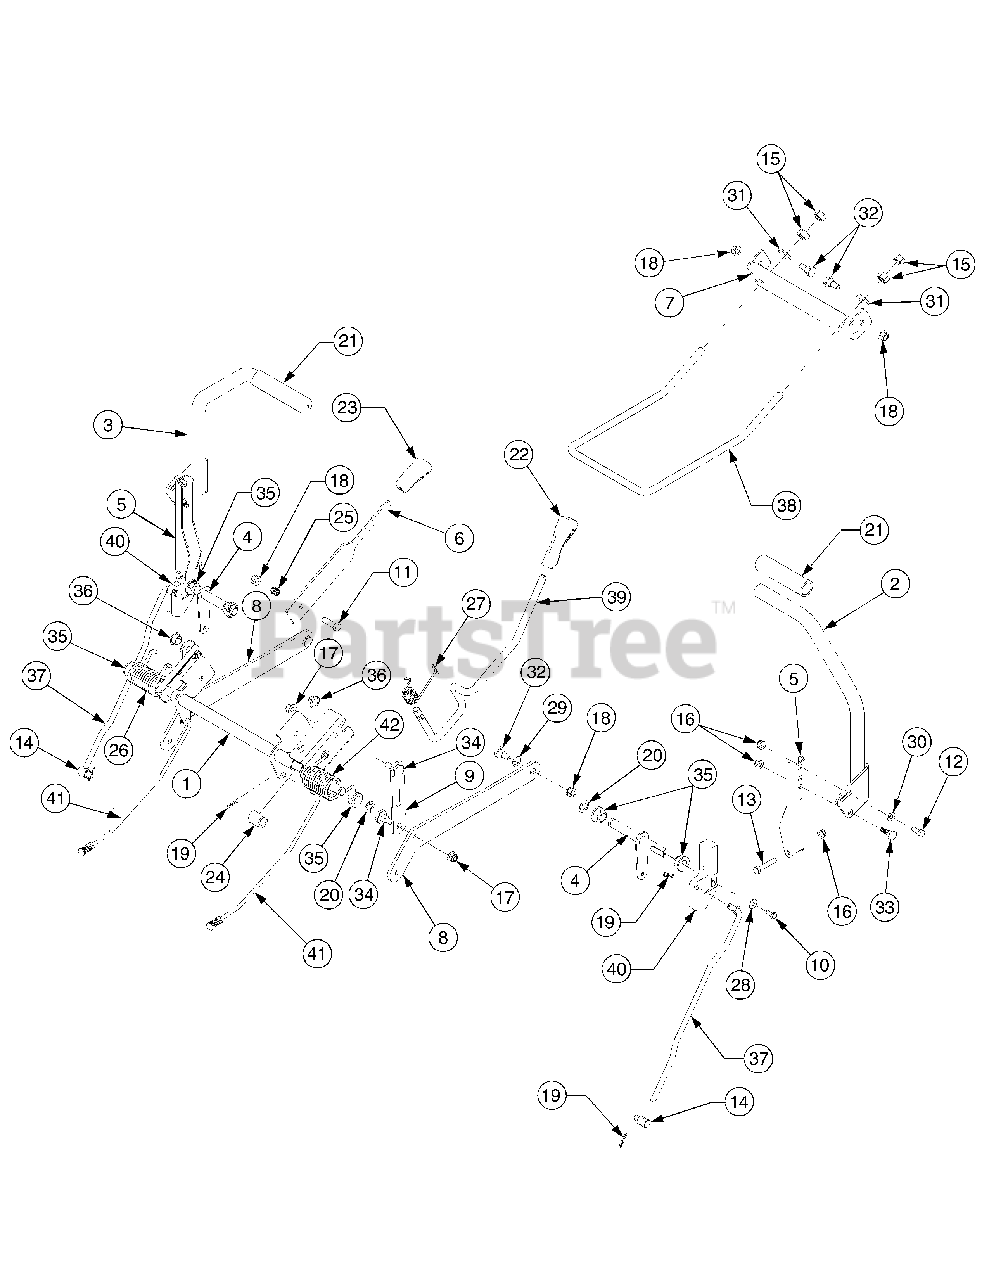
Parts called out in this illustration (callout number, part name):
4	Shaft, Control
5	Bracket, Lapbar Pivot
10	Screw, Hex Lock, 1/4-20 x .62 GR5
11	Screw, Hex Cap, 3/8-16 x 1.25 GR5 ...
12	Screw, Hex Cap, 5/16-18 x .75 GR5 ...
13	Screw, Hex Cap, 5/16-18 x 1.75 GR5
14	Ferrule, 3/8-24 x .375
15	Nut, Hex, 1/2-13 GR5
16	Nut, Hx Flange Insert Lck, 5/16-18 GrF
17	Nut, Hx Flange Insert Lck, 3/8-16GrF
18	Nut, Hex Flange Lock, 3/8-16 GRF
19	Pin, Internal Cotter
20	E-Ring , .625 Dia. Shaft
22	Grip, Handle
24	Spacer, .62 x 1.0
25	Spring, Compression
26	Spring, Torsion LH - Model ZT 5000 ONLY
27	Spring, Torsion
28	Washer, Bell, .265 x .75 x .062
29	Washer, Flat, .51 x 1.0 x .06
30	Washer, Flat, .344 x .688 x .065
31	Washer, Flat, .531 x 1.062 x .134 HT ..
32	Screw, Shoulder, .498 x .340:3/8-16
33	Screw, Shoulder, .437 x .268:5/16-18
34	Screw, Shoulder, .5 x .434:3/8-16
35	Bearing, Hex Flange
36	Bearing, Flange, .626 x .938 x .344
37	Rod, Lapbar Control
38	Rod, Deck Front Hanger
39	Rod, Deck Lift Handle
42	Spring, Torsion RH - Model ZT 5000 ONLY
